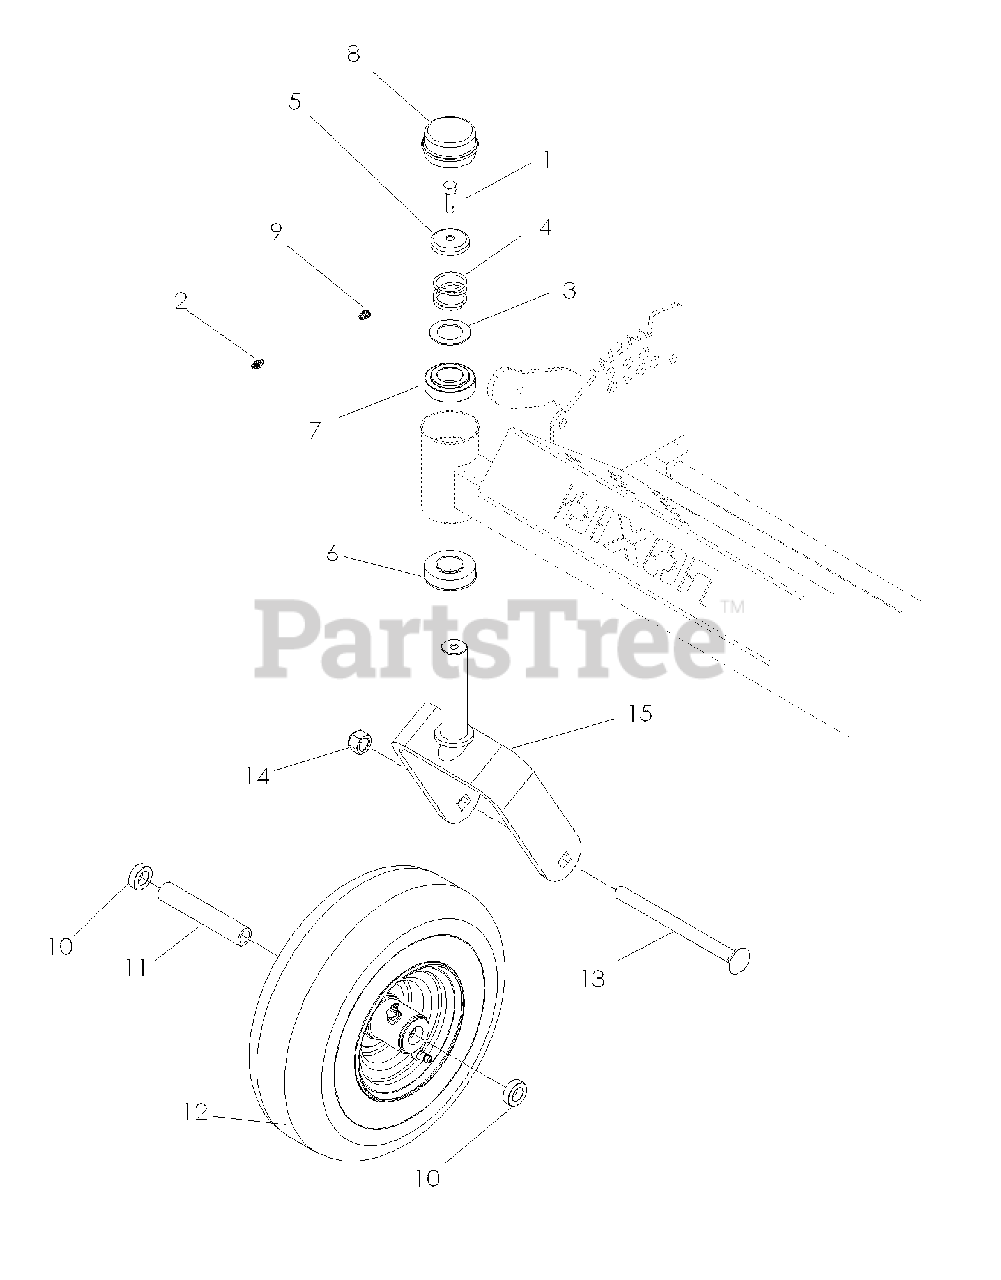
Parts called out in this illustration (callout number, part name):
1	5/16-18X1 HHB G5W/NY
2	ZERK, 3/16, DRIVE IN
3	WASHER, 1.025 ID X 1.64
4	SPRING, CASTER
5	CASTER.PLUG
6	BEARING
7	BUSHING, CASTER
8	GREASE CAP
9	GREASE ZERK-1/4"
10	SPACER, 5/16"
12	TIRE ASSEMBLY, BRG
13	RHSNB 1/2-13 X 6.50 GR2 ZD
14	NUT 1/2-13 HEX NYLOC ZD
15	CASTER DK BLUE
